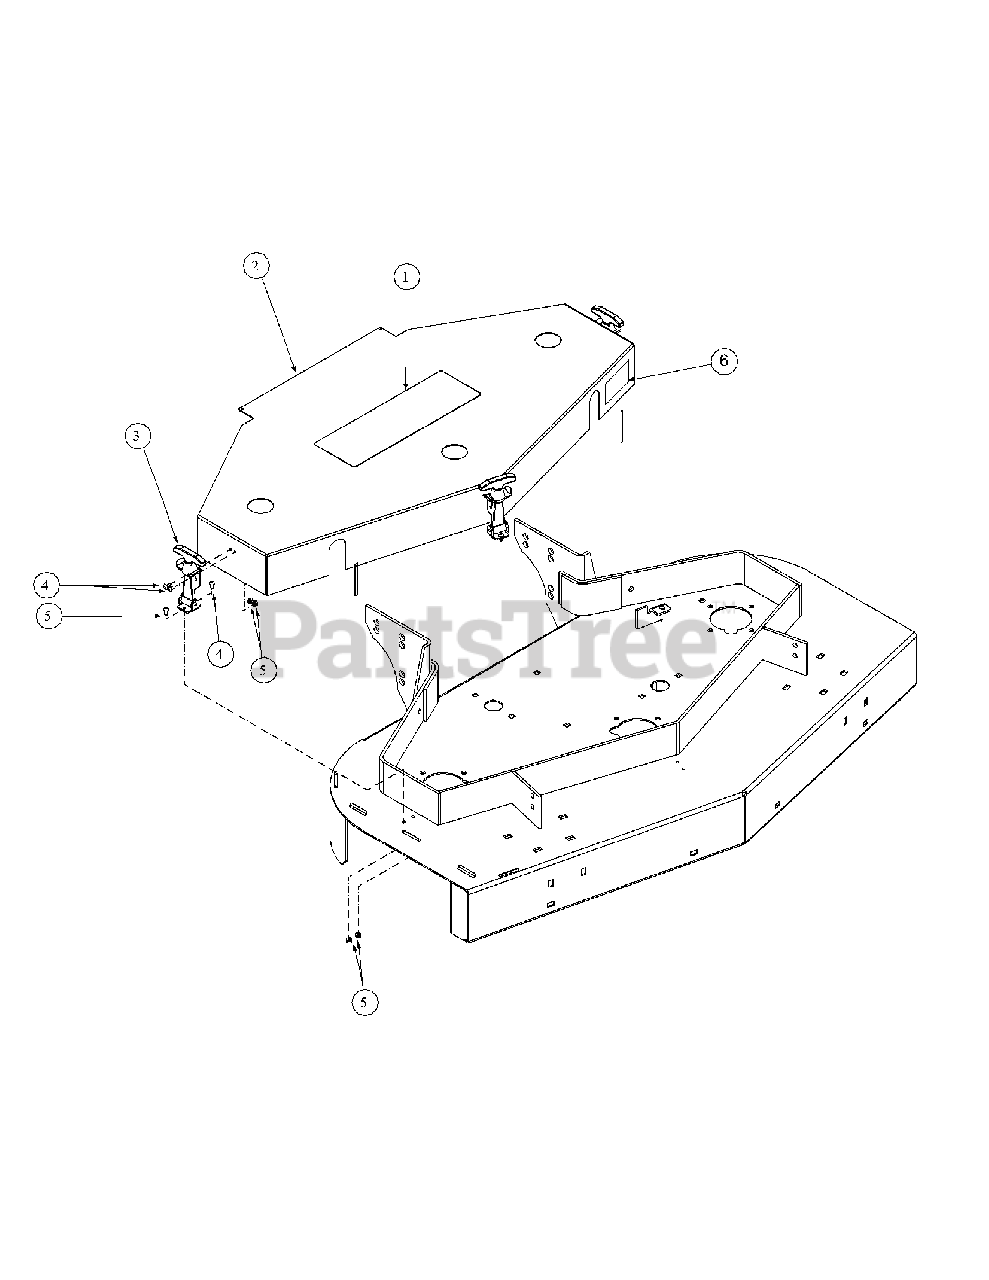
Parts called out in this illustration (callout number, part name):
1	Label Commercial Mower
2	Deck Cover 48"
3	Rubber Latch Hood
4	Machine Screw, 10-24 x 1/2
5	Lock Nut, Nylon Insert, #10-24
6	Label, G1548
